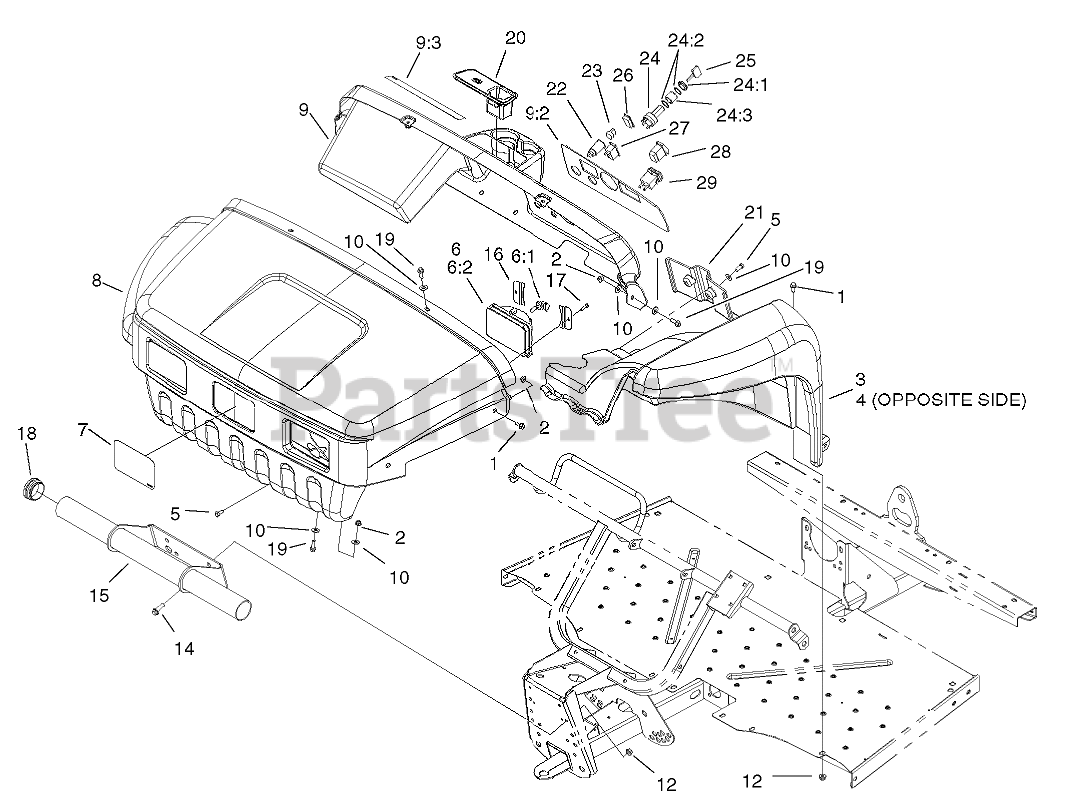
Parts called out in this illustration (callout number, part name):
1	SCREW-HHF
2	NUT-HF, NI
3	LH FENDER ASM
4	RH FENDER ASM
5	SCREW-HWH
6	HEADLIGHT
6:1	LAMP-12 VOLT
6:2	LENS-HEADLIGHT
7	DECAL
8	HOOD ASM
9	DASH ASM
9:2	DECAL-WARNING, DASH
9:3	DECAL-DANGER
10	WASHER-FLAT
12	NUT-HF, NI
15	BUMPER-TUBE
16	BRACKET-HEADLIGHT
17	SCREW-HWH
18	CAP-END
19	SCREW-HHF
20	PLUG-RUBBER
21	COVER-CHANNEL
22	POINT-POWER
24	Switch-Ignition
24:1	NUT-SWITCH, PLASTIC
24:2	WASHER-LOCK, INTERNAL
24:3	SPACER-SWITCH
25	KEY-IGNITION
26	PLUG-HOLE
27	INDICATOR-LIGHT, LOW-OIL PRESSURE
28	SWITCH
29	HOURMETER
